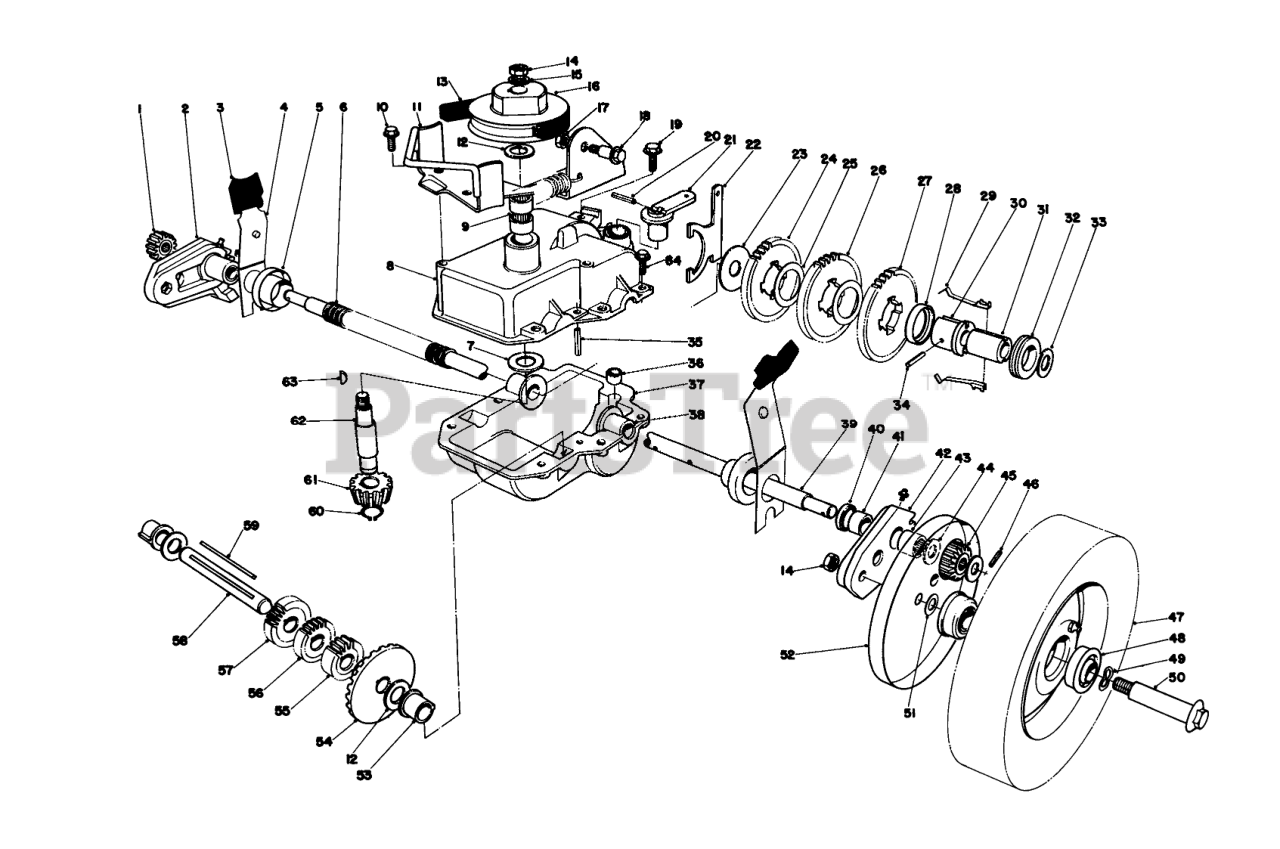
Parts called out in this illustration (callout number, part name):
1	RH CLUTCH & PINION
2	Pivot Arm R.H. (Incl. Ref. #40, 41 & 43)
3	KNOB-ARM
4	Spring Arm
5	End Cap
6	CONDUIT-CONVOLUTED, SPLIT
7	Thrust Washer
8	Upper Gear Case
9	Bearing
10	Screw
11	Belt Guide Bracket
12	WASHER-THRUST
13	V-BELT
14	Nut
15	WASHER-FLAT
16	PULLEY
17	NUT-HEX, SIDE DEFORM
18	Shoulder Bolt
19	SCREW-HWHTF
20	PIN-COIL
21	LEVER-SHIFT
22	Shift Yoke
23	WASHER
24	Gear 38T
25	WASHER
26	Gear
27	Gear
28	KEY RETAINER
29	KEY-SHIFT
30	Sleeve Body
31	Sleeve
32	COLLAR-SHIFT
33	WASHER-PLAIN
34	COIL PIN
35	ROLL PIN 3/16 X 1 IN
36	BUSHING-YOKE
37	LOWER GEAR CASE CAST
38	Bushing
39	OUTPUT SHAFT
40	Seal
41	Bushing
42	Pivot Arm L.H. (Incl. Ref. #40, 41 & 43)
43	Needle Baring
44	WASHER
45	LH CLUTCH & PINION
46	Pin
47	Wheel & Tire Assy. (Incl. Ref. #48)
48	BEARING-BALL
49	SPRING WASHER
50	WHEEL BOLT
51	WASHER
52	Cover-Wheel
53	Botching Shaft
54	Gear Bevel
55	14 T GEAR
56	16 T GEAR
57	GEAR-18T
58	MTG BRKT WA B
59	Key Square
60	RING-RETAINING
61	PINION-BEVEL
62	Input Shaft & Pinion Assembly (Incl. Ref. #61)
63	KEY-WOODRUFF
64	SCREW-HWH, THREAD ROLL
